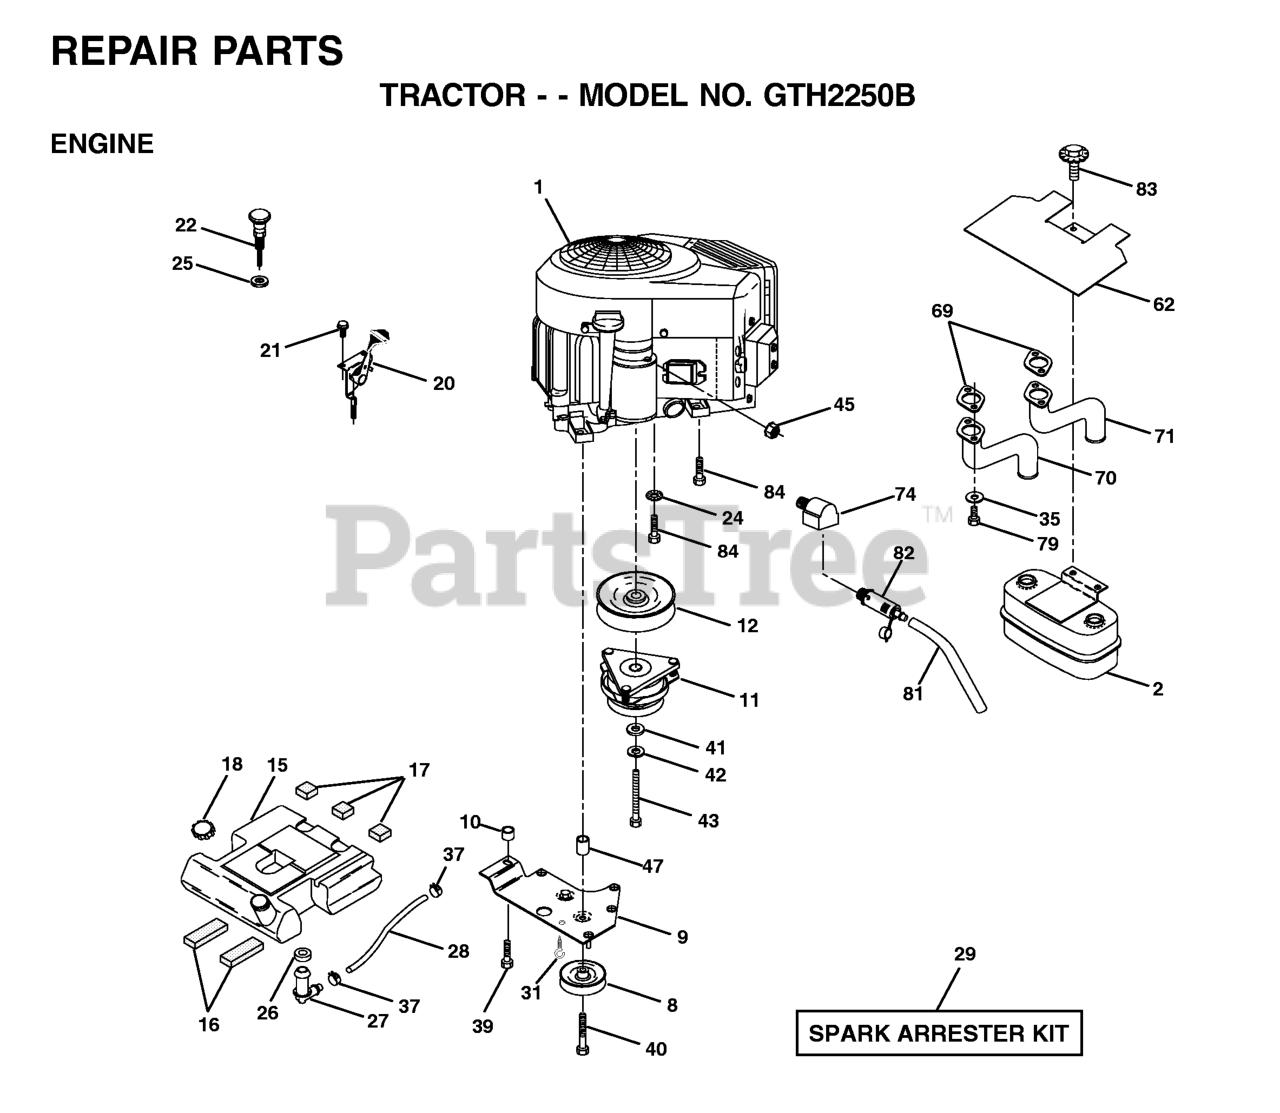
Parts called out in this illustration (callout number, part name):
2	MUFFLER.TWIN.CYL.LOW.TONE
8	RP.IDLER GROOVED
9	KEEPER ASM BELT ENGINE
12	PULLEY ENG VGT ELECT CLUTCH
15	FUEL TANK 3.5G
16	PAD IDLER TI
17	PAD-SPACER LT
18	CAP, FUEL GUAGE
20	THROTTLE CABLE
21	SCREW
22	REPL BY 532 1754-40
24	LOCKWASHER
25	Nut Keps 3/8 - 24 UNF
26	BUSHING OUTLET T
27	STEM FUEL TANK
28	FUEL LINE
29	KIT.SPARK ARRESTOR 794945 B&S
35	WASHER.LOCK.HVY.HLCL.SPR.5/16
37	HOSE CLAMP
39	SCREW TT 3/8-16X2-1/4 UNC
40	Screw TT 3/8-16 x 4 unc
42	LOCKWASHER
43	BOLT HEX 7/16-20X4-1/4"
45	NUT
62	RP SHIELD HEAT MUFFLER
69	GASKET.MUFFLER
70	TUBE.EXHAUST.B&S.VGT.LH
71	TUBE.EXHAUST.B&S.VGT.RH
74	ELBOW STREET BRASS
79	SCREW
81	TUBE, DRAIN OIL ASM.
82	PLUG, OIL DRAIN EASY
83	BOLT.5/16-18UNCX3/4 W/SEMS.BLK
84	SCREW 3/8-16 X 1-1/2
